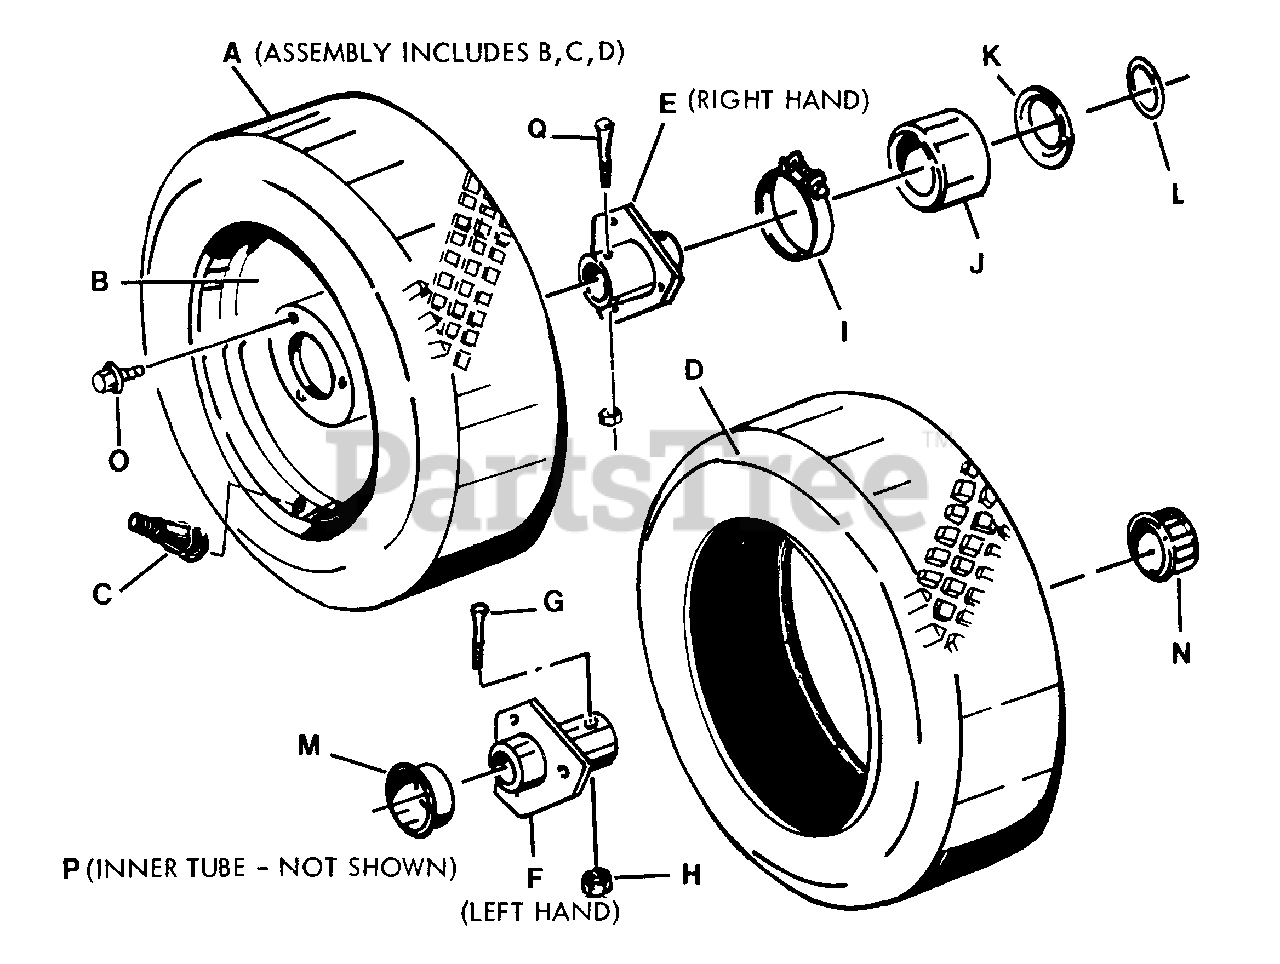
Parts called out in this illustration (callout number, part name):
A	WHEEL/TIRE - ASSEMBLY STD. 4. 80 - 4.00 x 8
B	RIM
C	STEM, VALVE
D	TIRE, 16 x 4.80 - 8
E	HUB, R.H. WHEEL
F	HUB, L. H. WHEEL
G	BOLT, TAPERED
H	NUT, 5/16-24 GRADE 5 LOCK
I	CLAMP
J	SEAL - CAP (RIGHT HAND)
K	SEAL, OIL
L	RING, CLAMP
M	CAP, Seal L.H. 3/4"
N	CAP, REAR WHEEL HUB
O	BOLT, LUG 1/2F x 3/4
Q	BOLT, TAPERED
